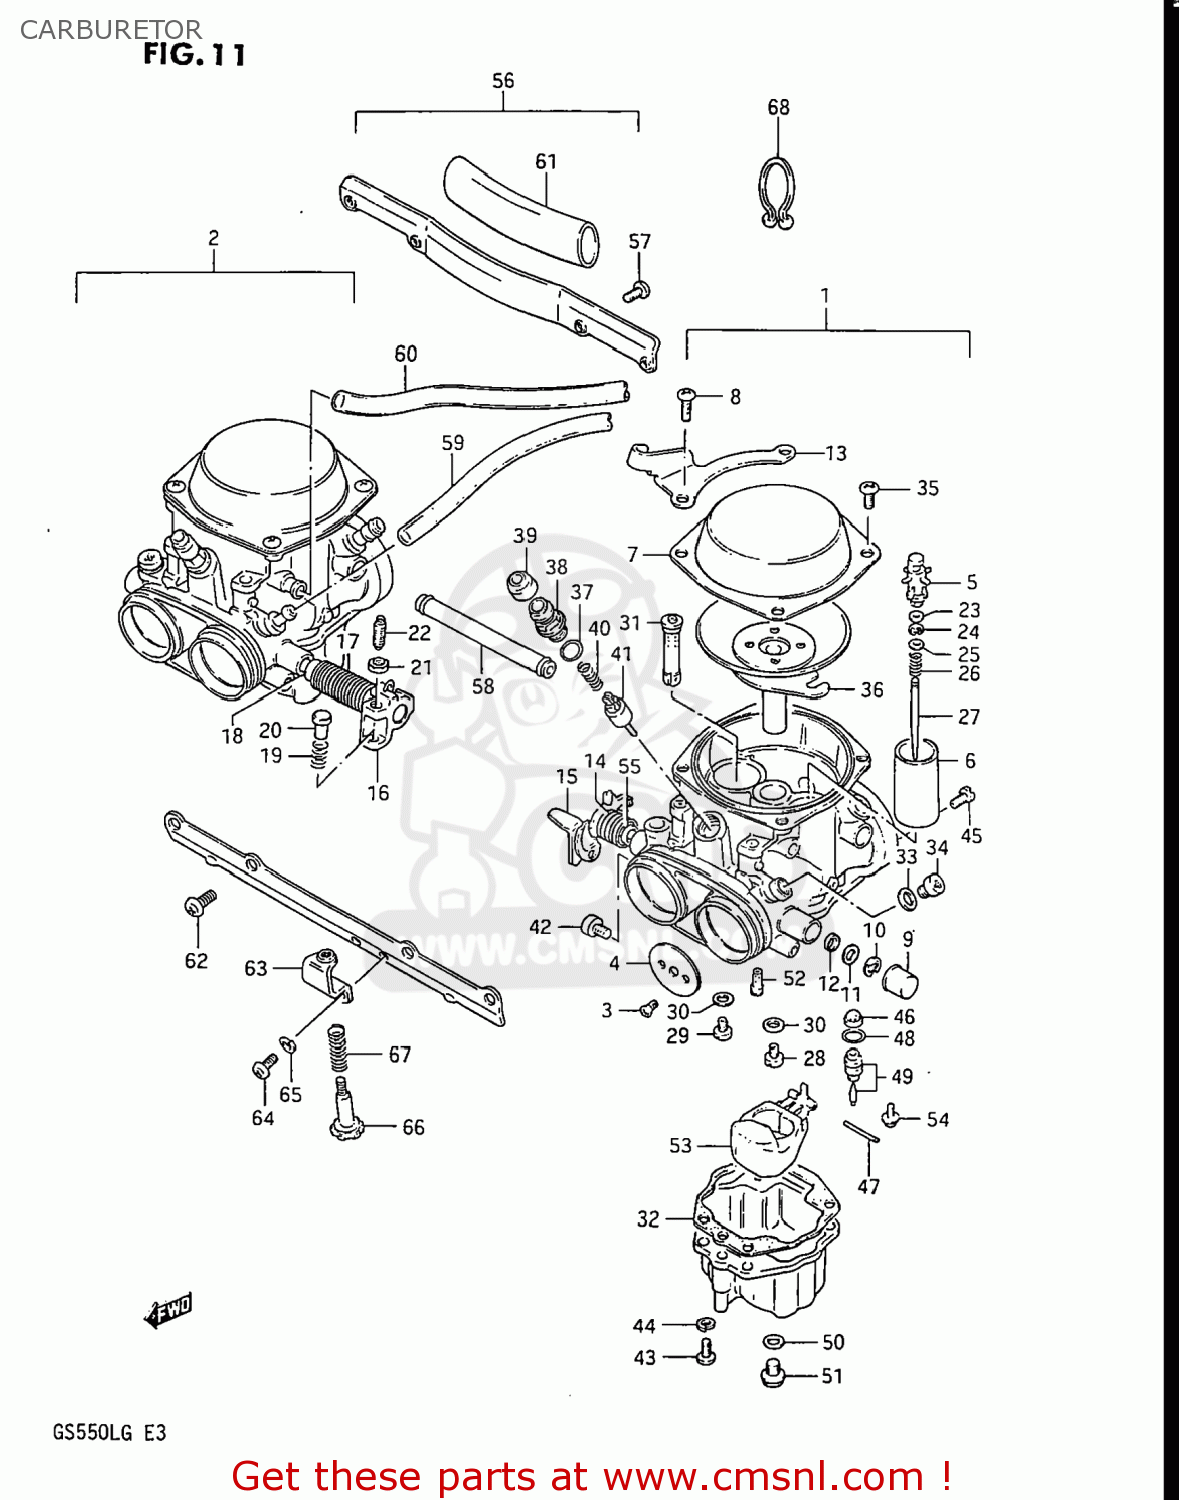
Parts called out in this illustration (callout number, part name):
1	CARBURETOR ASSEMBLY
2	CARBURETOR ASSEMBLY
3	SCREW
4	VALVE,THROTTLE
5	HOLDER,GUIDE
6	VALVE,THROTTLE
7	COVER,DIAPHRAGM
8	SCREW
9	CAP,THROTTLE SHAFT
10	E RING
11	GASKET,THROTTLE SHAFT (NAS)
12	SEAL
13	BRACKET,THROTTLE CABLE
14	SPRING,THROTTLE SHAFT
15	SHAFT ASSEMBLY
16	SHAFT ASSEMBLY
17	SPRING
18	RING
19	SPRING,THROTTLE SCREW
20	PIN,THROTTLE LEVER
21	NUT
22	SCREW
23	RING
24	CAP,LEVER
25	WASHER
26	SPRING
27	NEEDLE JET
28	JET,MAIN(90)
29	JET,MAIN(97.5)
30	WASHER,NEEDLE NOZZLE
31	JET,NEEDLE
32	GASKET,FLOAT CHAMBER (MCA)
33	WASHER
34	SCREW
35	SCREW
36	DIAPHRAGM,CARBURETOR
37	O RING
38	HOLDER,GUIDE
39	CAP
40	SPRING
41	VALVE,STARTER
42	SCREW
43	SCREW
44	LOCK WASHER
45	JET,PILOT(150)
46	FILTER
47	PIN,FLOAT
48	O-RING,NEEDLE VALVE
49	VALVE ASSEMBLY,NEEDLE
50	GASKET (NAS)
51	PLUG,DRAIN
52	JET,PILOT(37.5)
53	FLOAT
54	SCREW
55	RING,THROTTLE SHAFT
56	FLANGE ASSEMBLY,CARBURETOR
57	SCREW
58	PIPE,CARBURETOR
59	HOSE 4.5X8X390
60	HOSE
61	HOSE(16X19X100)
62	SCREW
63	BRACKET,SLOW ADJUST
64	SCREW
65	WASHER,LOCK
66	ADJUSTER
67	SPRING
68	CLIP(ID:16)
